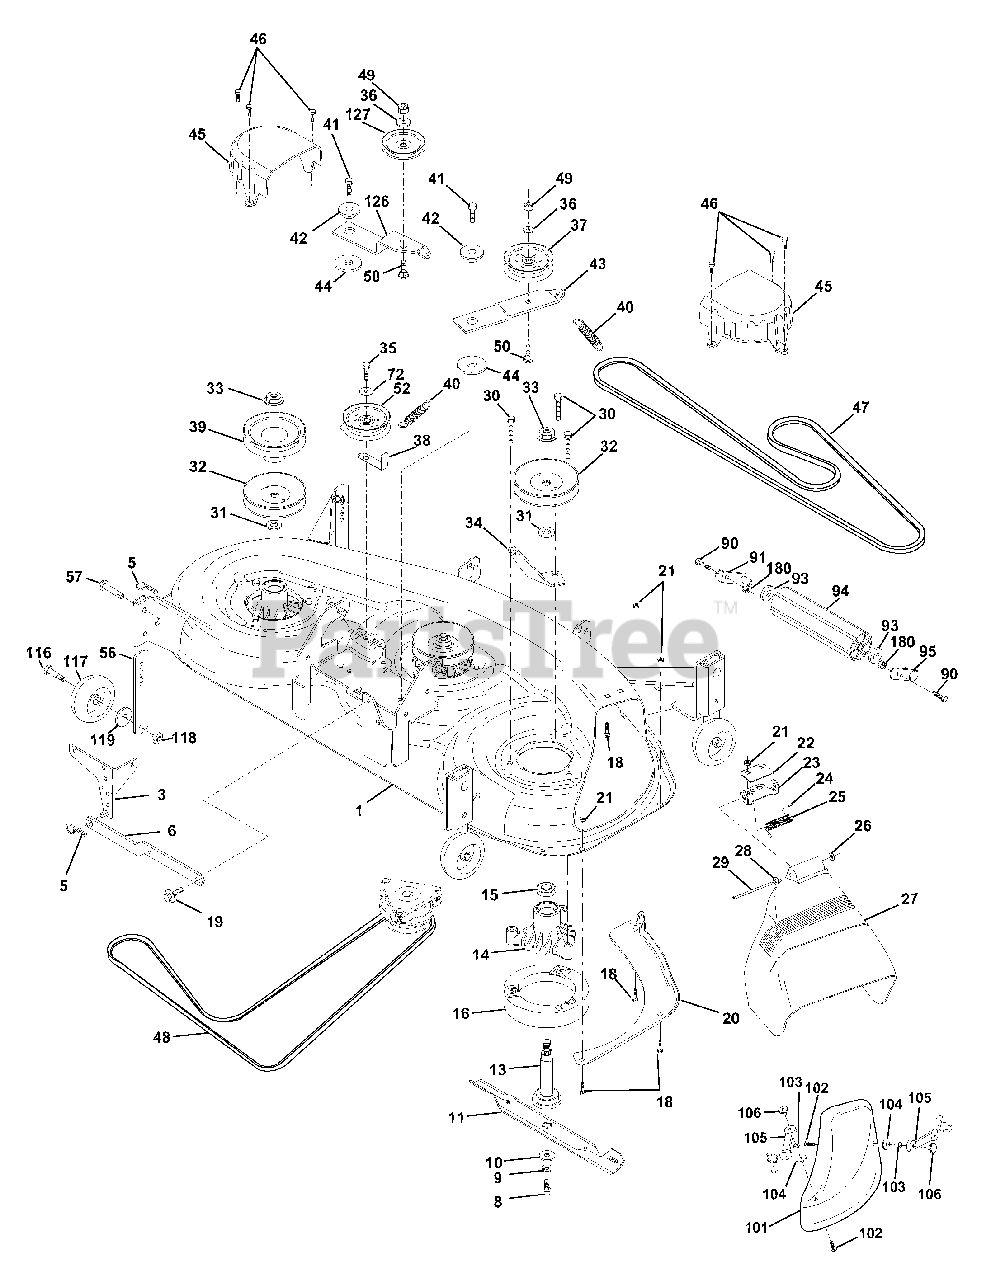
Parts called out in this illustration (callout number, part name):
1	Deck Asm., Mower 46"
3	Bracket Asm., Sway Bar
5	Retainer Spring
6	Arm, Suspension, Rear (Sway Bar)
8	Bolt, Patched 3/8-24 x 1-1/4 Gr. 8
9	Washer, Lock Hvy., Unplated 3/8
10	Washer, Hard Blade, Mower Vented
11	Blade, 46" Hi Perf
11	Blade, 46" Mulching
13	Shaft Asm. w/Lower Bearing
14	Housing, Mandrel
15	Bearing, Ball, Mandrel
16	Stripper, Mower Round
18	Bolt, Carriage 5/16-18 x 5/8
19	Bolt, Hex Head, Shoulder 5/16-18
20	Baffle, Vortex Mower 46"
21	Nut, Crownlock 5/16-18 UNC
22	Stiffener, Bracket
23	Bracket, Deflector
24	Cap, Sleeve
25	Spring, Torsion, Deflector
26	Nut, Push
27	Shield, Deflector Mower
28	Washer 11/32 x 5/8 x 16 Ga.
29	Rod, Hinge
30	Screw, Wsh Head, Thdroll
31	Washer, Spacer Mower Vented
32	Pulley, Mandrel
33	Nut, Flg. Top Lock Cntr. 9/16
34	Anchor, Spring Deck 46"
35	Screw, Thdroll 3/8-16 x 1-3/4 Tytt
36	Washer 13/32 x 13/16 x 16 Ga.
37	Pulley, Idler, Flat
38	Keeper, Belt, Idler
39	Pulley, Idler, Driven
40	Spring, Secondary 44/46/50 Vent
41	Screw 3/8-16 x 1-1/4
42	Spacer, Retainer
43	Arm, Idler Secondary
44	Washer,Hardened
45	Cover, Mandrel Deck
46	Screw, Thdroll. 1/4-20 x 5/8
47	V-Belt, Mower, Secondary
48	V-Belt, Mower, Primary
49	Nut, Crownlock 3/8-16 UNC
50	Bolt, Carriage 3/8-16 x 1-1/2 Gr. 5
52	Pulley Idler 46 Pri. Drive
53	Washer 13/32 x 13/16 x 12
54	Bolt Fin Hex 3/8-16 x 1
55	Bolt Rdhd 3/8-16 x 1
56	Bar Adjusting Gage wheel
57	Pin Head Rivet
72	Washer 13/32 x 1 x 16 Ga.
91	Bracket, Asm Noseroller, LH
92	Nut, Lock, Hex w/Ins 3/8-16UNC
93	Washer 17/32 x 7/8 x 16 Ga.
94	Roller, Nose 38 & 42
95	Bracket, asm Noseroller RH
101	Cover Mulcher 46" Black
102	Screw Phillips Truss Head
103	Washer Lock #10
104	Washer #10
105	Latch Asm mulch/Bagger
106	Nut Weld
116	Bolt, Shoulder
117	Gauge Wheel
118	Nut, Centerlock 3/8-16 UNC
119	Washer 3/8 x 7/8 x 14 Ga.
126	Arm, Idler, Primary Deck 46"
127	Pulley, Idler, V-Groove Dim. 4.25
